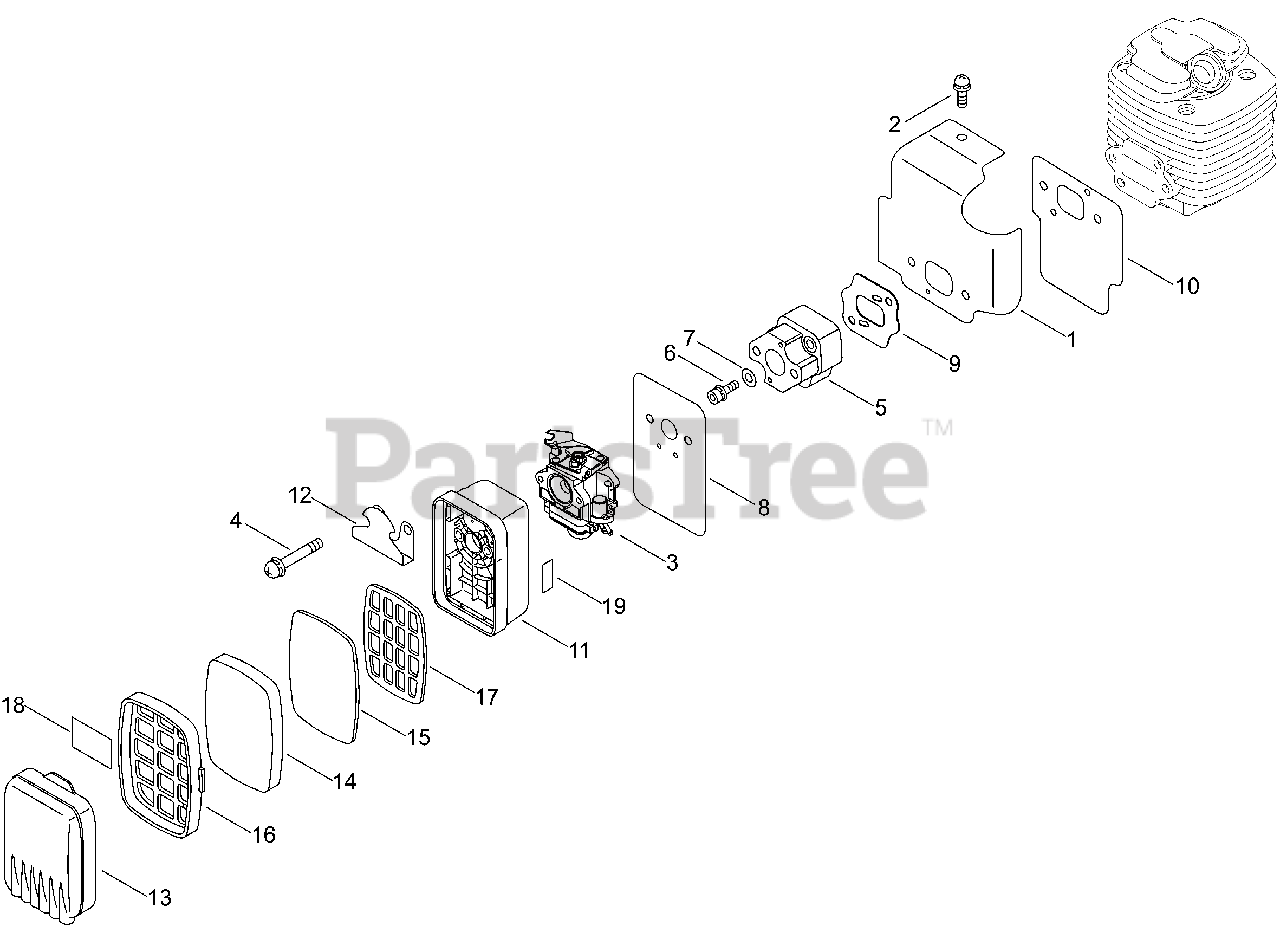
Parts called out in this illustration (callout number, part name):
1	COVER, ENGINE - INTAKE
2	SCREW 5×10
3	CARBURETOR WYK-504
4	SCREW 5×60
5	INSULATOR, INTAKE
6	BOLT 5×30
7	WASHER 5.5×10×2.3
8	GASKET, INTAKE
9	GASKET, INTAKE
10	GASKET, INTAKE
11	CASE ASSY, AIR FILTER
12	PLATE, PREVENT
13	COVER, AIR FILTER
14	PRE-FILTER, FOAM
15	FILTER, AIR
16	GRID, PRE-FILTER
17	GRID, AIR FILTER
18	LABEL, AIR FILTER
19	LABEL, CHOKE
